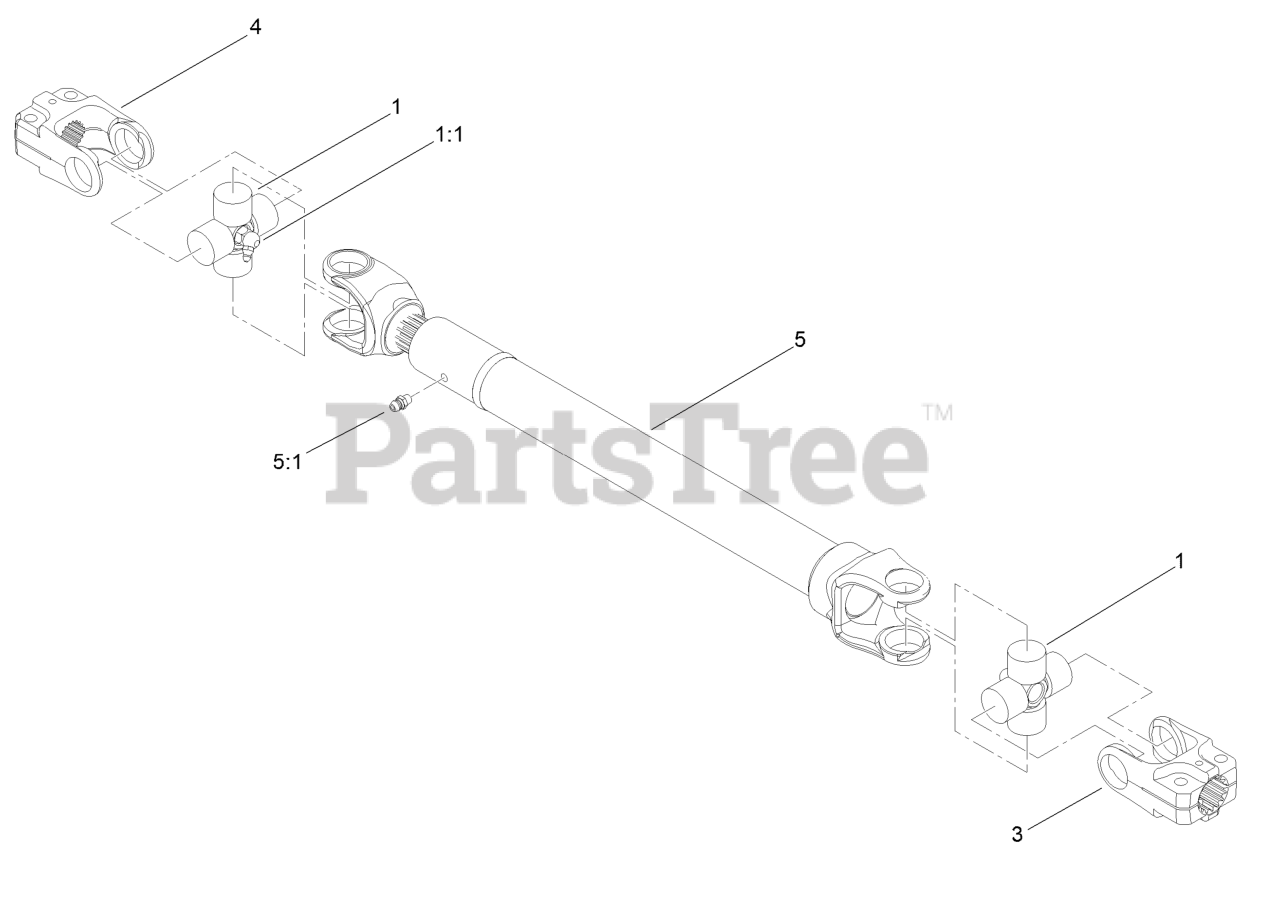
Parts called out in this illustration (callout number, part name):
1	Cross And Bearing Kit
1:1	Fitting-Grease
3	Yoke-End
4	Yoke-End
5	Tube-Yoke, Slip
5:1	Fitting-Grease
